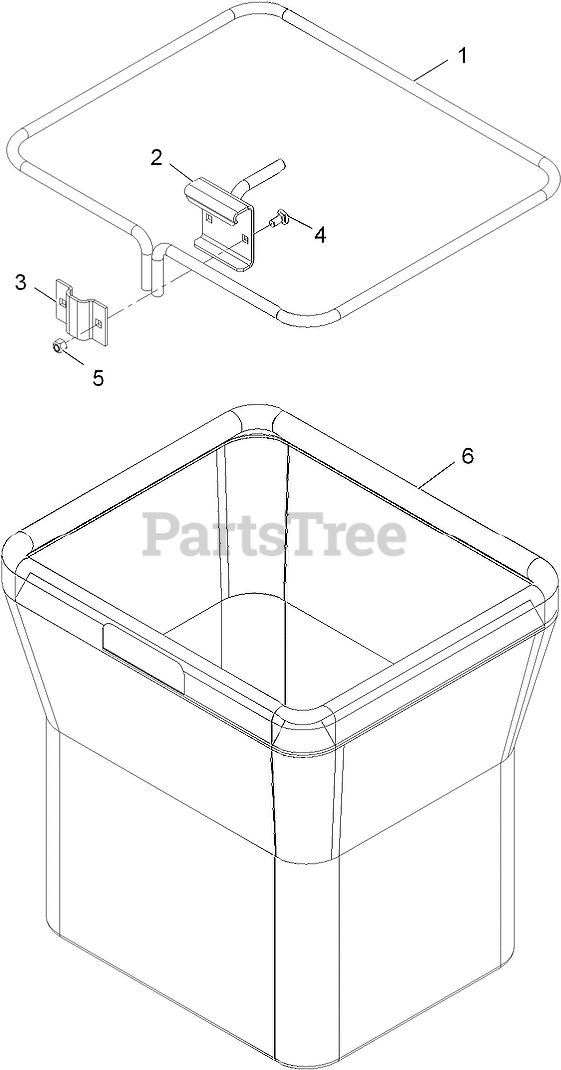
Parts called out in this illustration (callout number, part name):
1	FRAME-BAG
4	BOLT-CARR
5	NUT-LOCK, NI
6	BAG,20 IN. DEPTH
